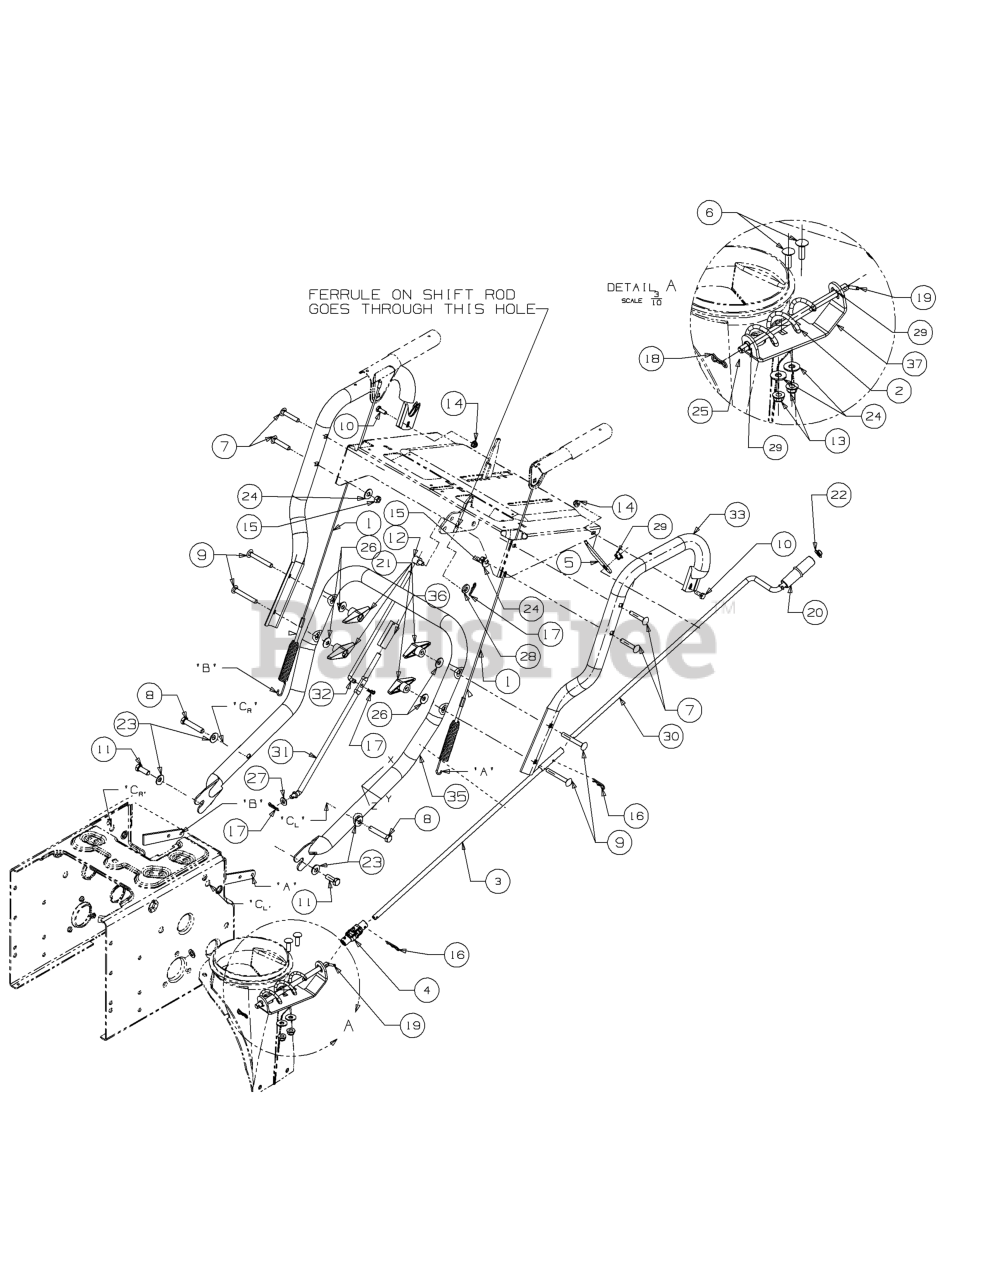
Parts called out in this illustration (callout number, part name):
1	Auger/Drive Engagement Cable
2	Spiral-Crank Chute
3	Rod Asm-Chute Cran
4	Block Assy-Joint
5	Bracket-Chu
6	Carriage Bolt 5/16-18 X 1.00
7	Bolt-Carriage 5/16
8	Hhcs-3/8-16:2.00
9	Bolt-Carriage
10	Screw-Hex 1/4-20X.
11	Screw-Hex Patch 3/
12	Engagement Ferru
13	Nut-Flglk 5/16-18
14	Nut-Flglk
15	Nut-Hex Center L
16	Pin-Intern Cot-1
17	Pin:Cot:.072 Dia
18	Pin-Cotter
19	Pin-Spring Roll .1
20	Chute Crank Knob
21	Knob-Wing Nut
22	Nut-Push
23	Washer-Bell .400 I
24	Washer-Fl
25	Washer-Fl
26	Washer-Bell .337 X
27	Washer-Fl
28	Washer-Fl.344
29	Bushing .380 Id
30	Crank-Chute
31	Rod-Lower Shift
32	Rod-Upper Shift 5/
33	Handle-Upper LH
33	Handle-Upper RH
35	Handle-Lower
36	Rod-Clutch Lock
37	Bracket-Chute Crank
